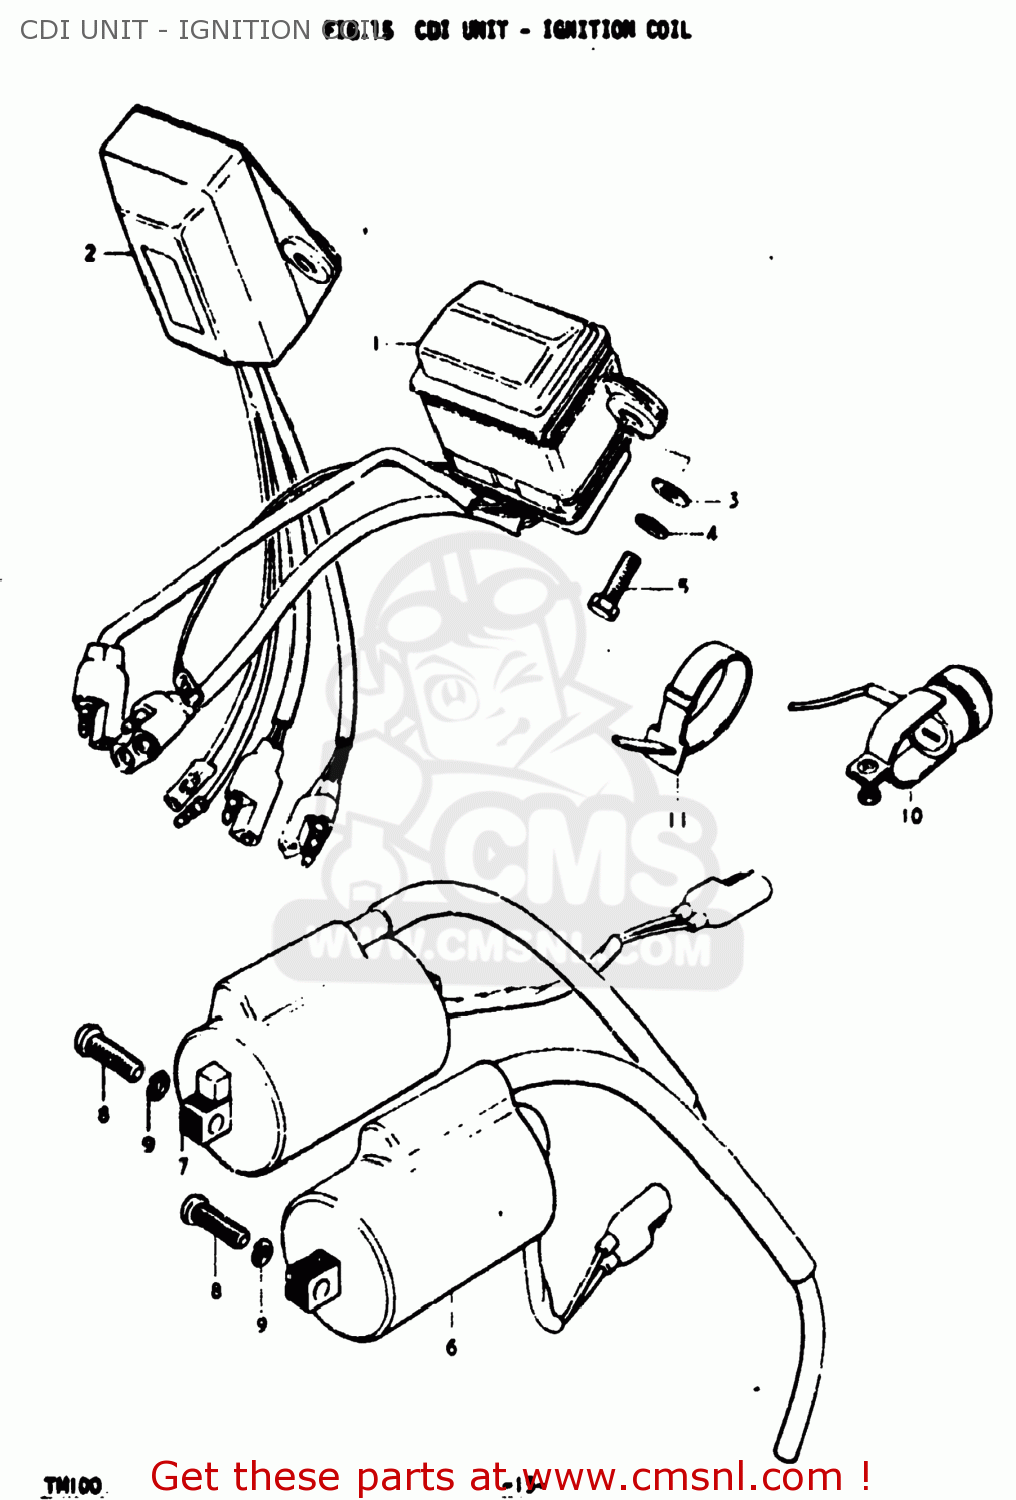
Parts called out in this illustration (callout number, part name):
2	CDI UNIT ASSY
3	WASHER 6MM
4	LOCK WASHER
5	BOLT
6	COIL ASSEMBLY,IGNITION
7	COIL ASSEMBLY,IGNITION
8	SCREW
9	LOCK WASHER
10	SWITCH ASSEMBLY
11	CLAMP
